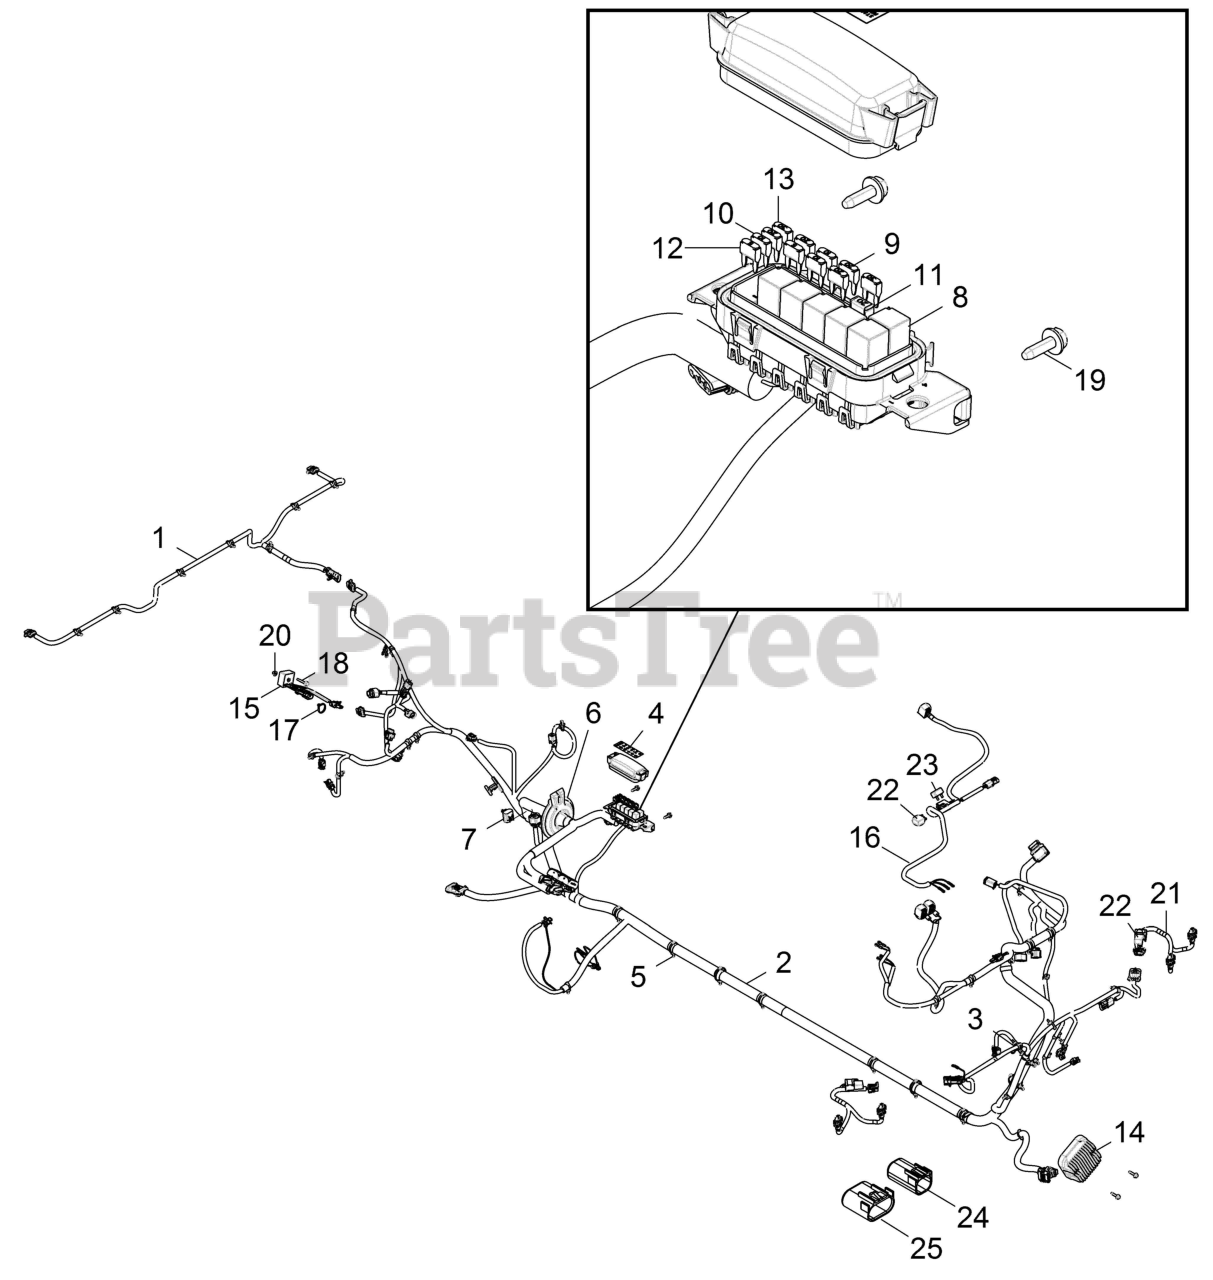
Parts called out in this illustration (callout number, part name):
1	HARNESS-BOX-ARIENS SPLY
2	HARNESS, CHASSIS, 570 CREW EPS
3	CABLE TIE
4	DECAL, RELAY/FUSE BLOCK
5	CLIP-ROUTING
6	GROMMET-CHASSIS HARNESS
7	COVER-DIAGNOSTIC,W/CLIP
8	RELAY-SPST,SERIES 303,SEALED
9	FUSE,PARK,20 AMP,(10)
10	FUSE,IGN.10 AMP,(10)
11	BREAKER-CIRCUIT,20 AMP
12	FUSE-5A,MINI BLADE
13	FUSE,MAIN,30 AMP,(10)
14	REGULATOR-3PH,50A,SERIES,HISPD
15	RELAY, SOLID STATE,9A,LONG LD
16	HARNESS-BOX,LIFT
17	CABLE TIE (10)
18	BOLT-M6X1.0X35,HXFLG/SH-OLV D
19	SCR-TFHFL-M6X1.0X25,ZOD
20	NUT-M6X1.0,FLG-NYLOC-OLIVE D
21	HARNESS-HEADLIGHT,ARIENS
22	RELAY-MICRO,SPST,35A,SEALED
23	BREAKER-CIRCUIT,20 AMP,SEALED
24	CONNECTOR-CAP,EPS SIGNAL
25	CONNECTOR-CAP,EPS POWER
